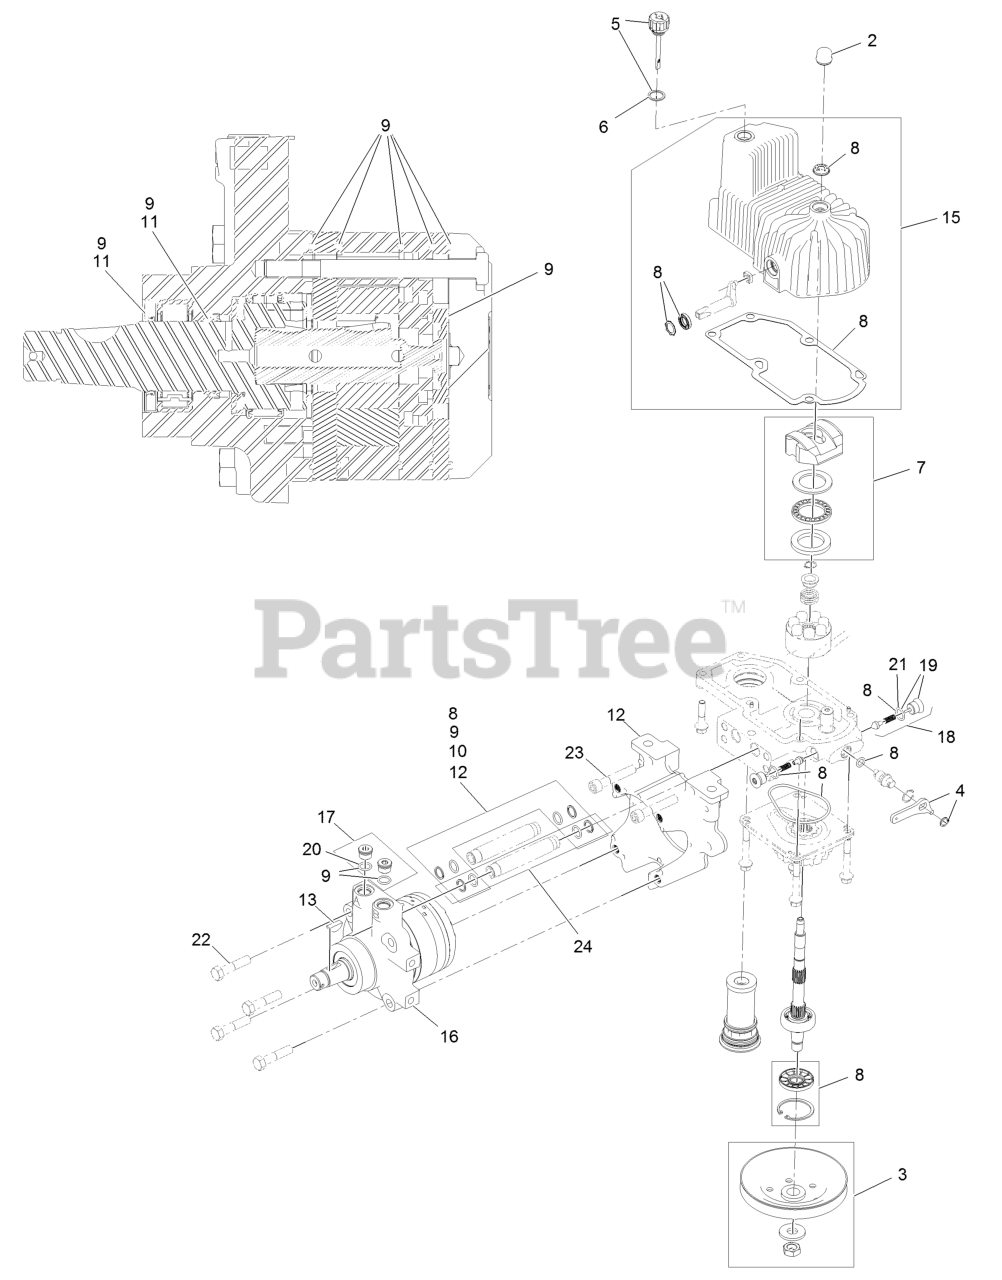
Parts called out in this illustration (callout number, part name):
2	COVER-SHAFT, HYDRO
3	PULLEY KIT
4	HANDLE-BYPASS VALVE, HYDRO
5	DIPSTICK-HYDRO W/GASKET
6	GASKET-DIPSTICK, HYDRO
7	SWASH BLOCK KIT
8	PUMP SEAL KIT
9	MOTOR SEAL KIT
10	TUBE SEAL KIT
11	OUTPUT SHAFT SEAL KIT
12	NOSE CUP-UHT
13	KEY-WOODRUFF
15	HOUSING-HYDRO, LH
16	MOTOR-HYDRAULIC LH 240CC
17	MAGNETIC PLUGS SERVICE KIT
18	CHECK VALVE ASM
19	PLUG-CHECK (W/O-RING)
21	O-RING-CHECK VALVE
22	SCREW HH
23	SCREW-HSH
24	HYDRAULIC TUBE KIT
